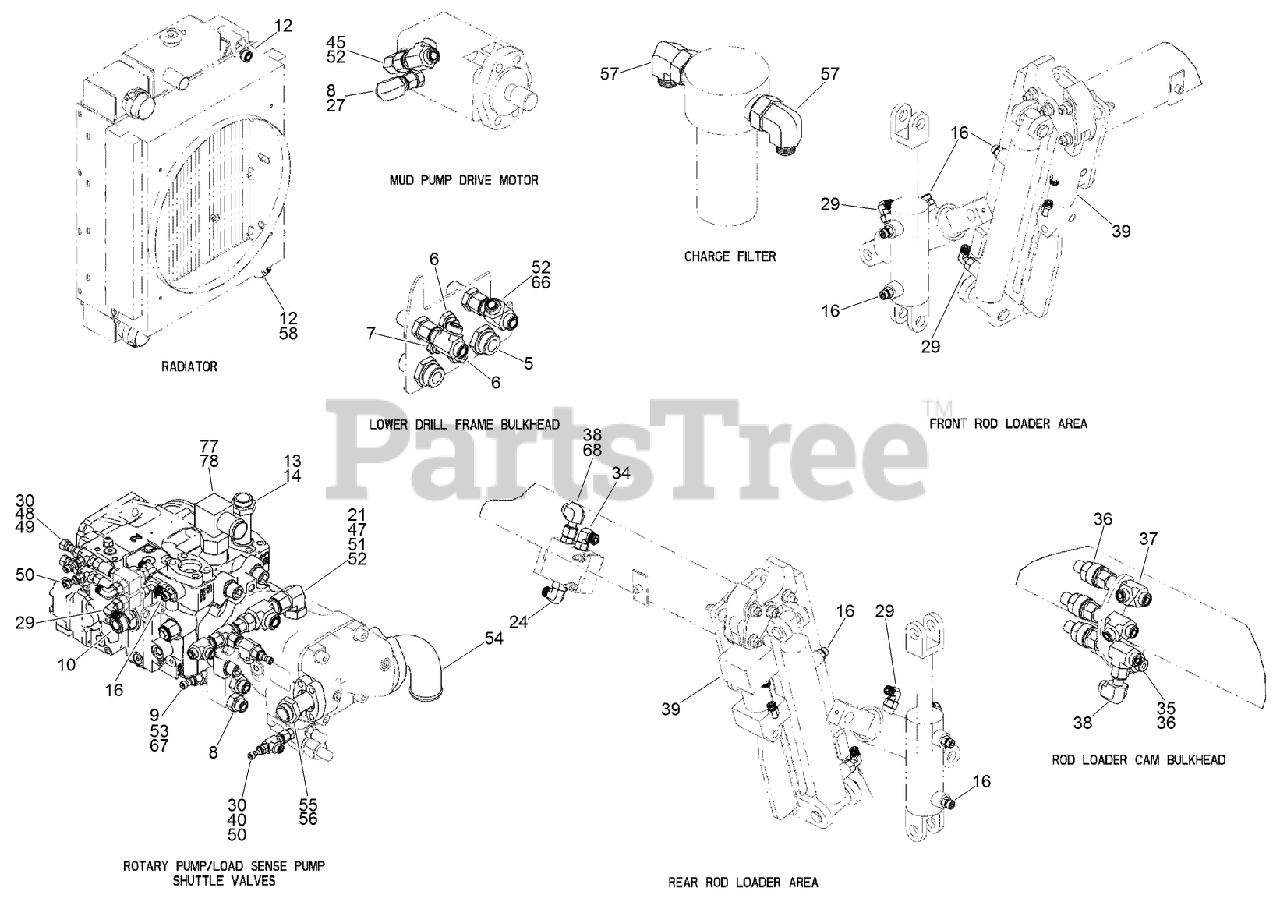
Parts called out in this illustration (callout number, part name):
6	CONNECTION - Straight, -12 ORFS / -8 ORB
7	FITTING-STRAIGHT
8	CONNECTION - Straight, -8 ORFS / -10 ORB
9	CONNECTION - Branch Tee, -6 ORFS / -6 ORB
10	CONNECTION - Straight, -12 ORFS / -12 ORB
12	CONNECTION - Straight, -12 ORFS / -16 ORB
13	ADAPTER-FLANGE, STRAIGHT
14	KIT - Split Flange, -16 SAE, w/O-Rings and Bolts
16	CONNECTION - Straight, -4 ORFS / -6 ORB
21	CONNECTION - 90 Degree, -4 ORFS / -4 ORB
24	CONNECTION - 90 Deg, -6 ORFS / -8 ORB
27	CONNECTION - 90 Deg, -8 ORFS / -8 ORFS
29	CONNECTION - 90 Deg, -4 ORFS / -6 ORB
30	CONNECTION - Run Tee, -4 ORFS / -4 ORFS
34	CONNECTION - 90 Deg, -6 ORFS / -6 ORB
35	CONNECTION - Straight, Bulkhead, ORFS
36	CONNECTION - Swivel, -6 ORFS
37	CONNECTION - Bulkhead, Run Tee, -6 ORFS / -6 ORFS
38	CONNECTION - 90 Deg, -6 ORFS / -6 ORFS
39	CONNECTION - 90 Degree, -4 ORFS / -4 NPT
40	CONNECTION - Straight, -4 ORFS / -4 ORB
45	CONNECTION - 90 Deg, -10 ORFS / -10 ORB
47	CONNECTION - Run Tee, -6 ORFS / -6 ORFS
48	FITTING-STRAIGHT
49	FITTING-STRAIGHT
50	NIPPLE-QD, DIAGNOSTIC
51	CONNECTION - 90 Degree, -10 ORFS / -12 ORB (Serial Numbers DD202480146 and Thereafter)
52	FITTING-TEE
53	NIPPLE-QD, DIAGNOSTIC
54	HOSE END - Formrite ORFC - 32 - 90
55	SPLIT FLANGE KIT
56	ADAPTER-FLANGE, STRAIGHT
57	CONNECTION - 90 Degree, -8 ORFS / -12 ORB
58	CONNECTION - 45 Degree, -12 ORFS / -12 ORFS
66	CONNECTION - Straight, Bulkhead, ORFS
67	CONNECTION, REDUCER, -4 ORFS / -7 ORFS
68	CONNECTION - Straight, -6 ORFS / -6 ORB
77	FITTING-STRAIGHT
78	FITTING-ELBOW, 90
